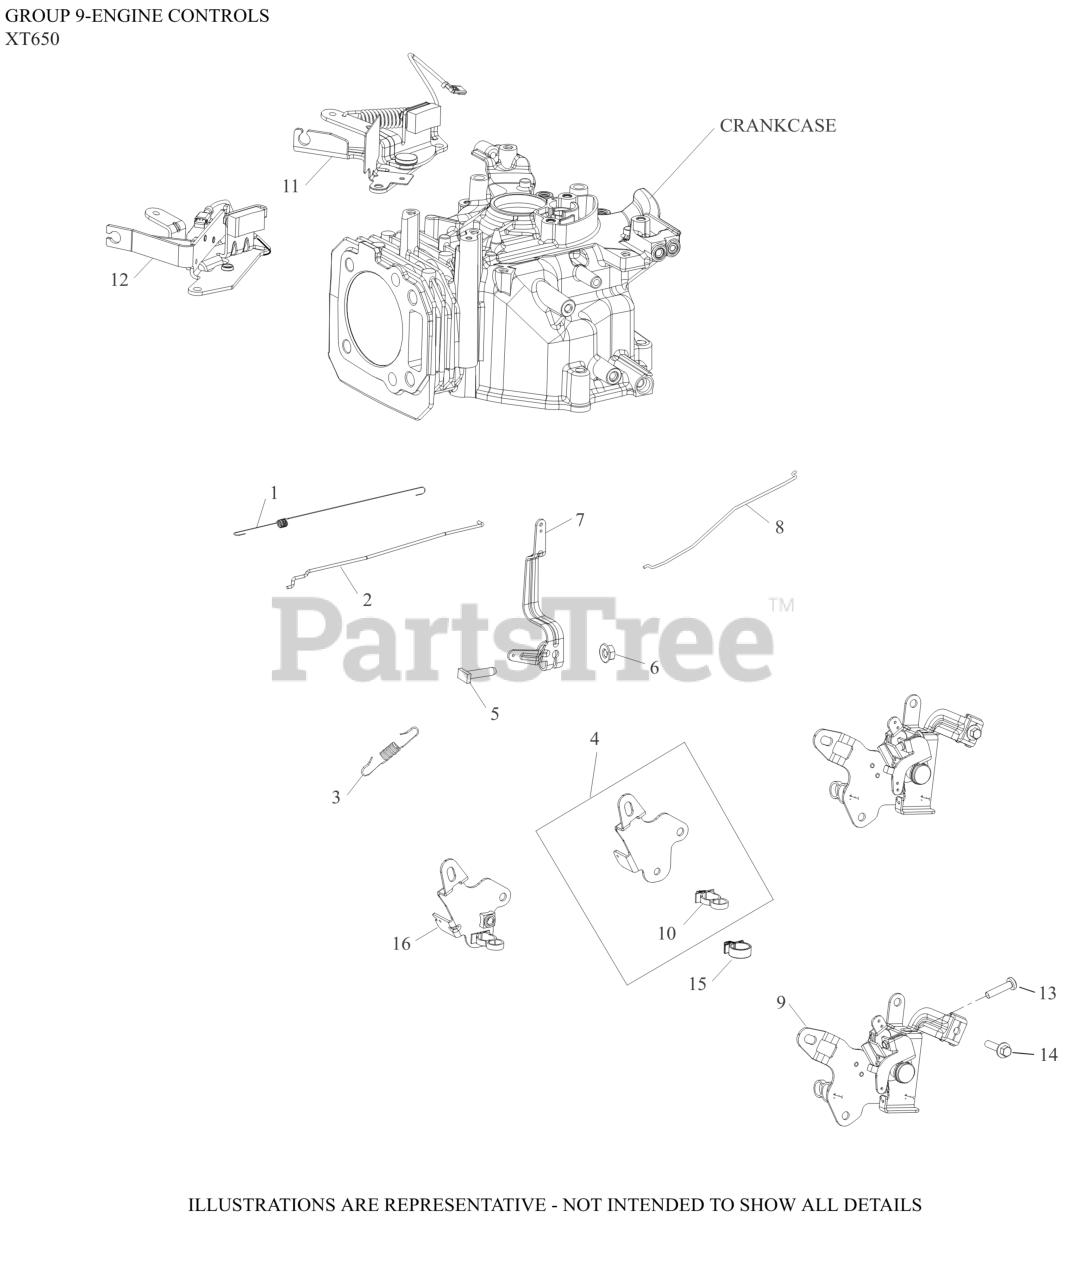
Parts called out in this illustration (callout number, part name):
1	SPRING, LINKAGE
2	LINKAGE, GOVERNOR-(#1407927S)
3	SPRING, GOV (2800-3300 RPM)
4	BRACKET ASSY-USE 14 126 81-S
5	SCREW, RECTANGLE HEAD (M6)
7	KIT GOVERNOR LEVER-(#1409033S)
